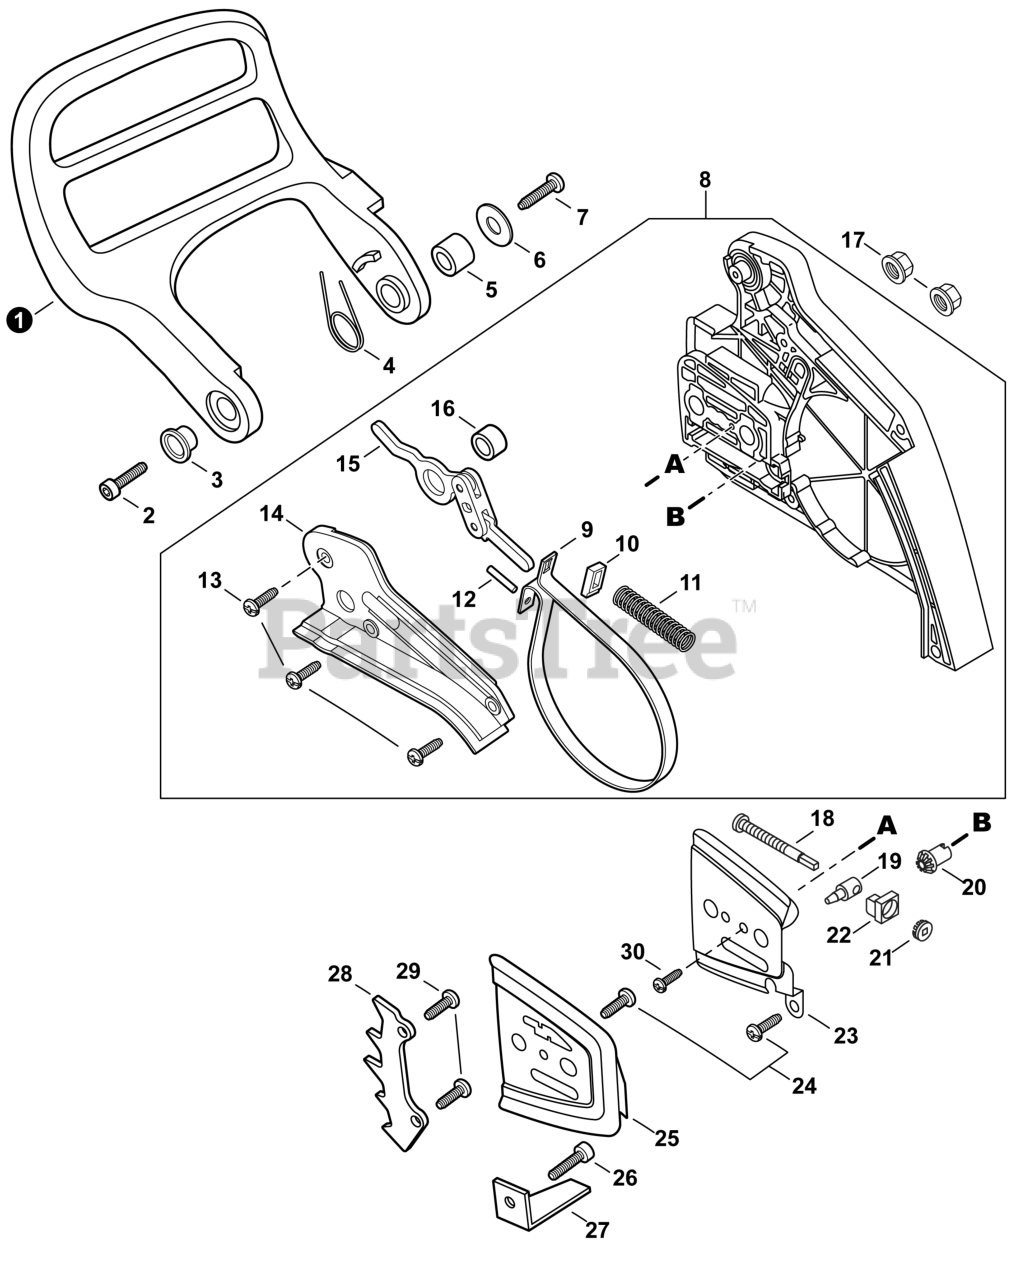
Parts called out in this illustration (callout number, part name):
1	LEVER, BRAKE
2	BOLT 5x16
3	COLLAR 10
4	SPRING, TORSION
5	SPACER 8x12x9
6	WASHER 4.2x16.5x1
8	BRAKE ASSY, CHAIN
9	BAND, BRAKE
11	SPRING, COMPRESSION
12	PIN, SPRING 3x9.8
13	SCREW 4x12
14	COVER, BRAKE
15	CONNECTOR, BRAKE
16	SPACER 8x12x9
17	NUT, FLANGE M8x1.25
18	SCREW, CHAIN TENSION
19	TENSIONER, CHAIN
20	GEAR, BEVEL
21	GEAR, BEVEL
22	COLLAR 8
23	PLATE, GUIDE - OUTER
24	SCREW 4x12
25	PLATE, GUIDE - INNER
26	BOLT 5x16
27	CATCHER, CHAIN
28	SPIKE, BUMPER
29	BOLT 5x20
30	SCREW 3x5
